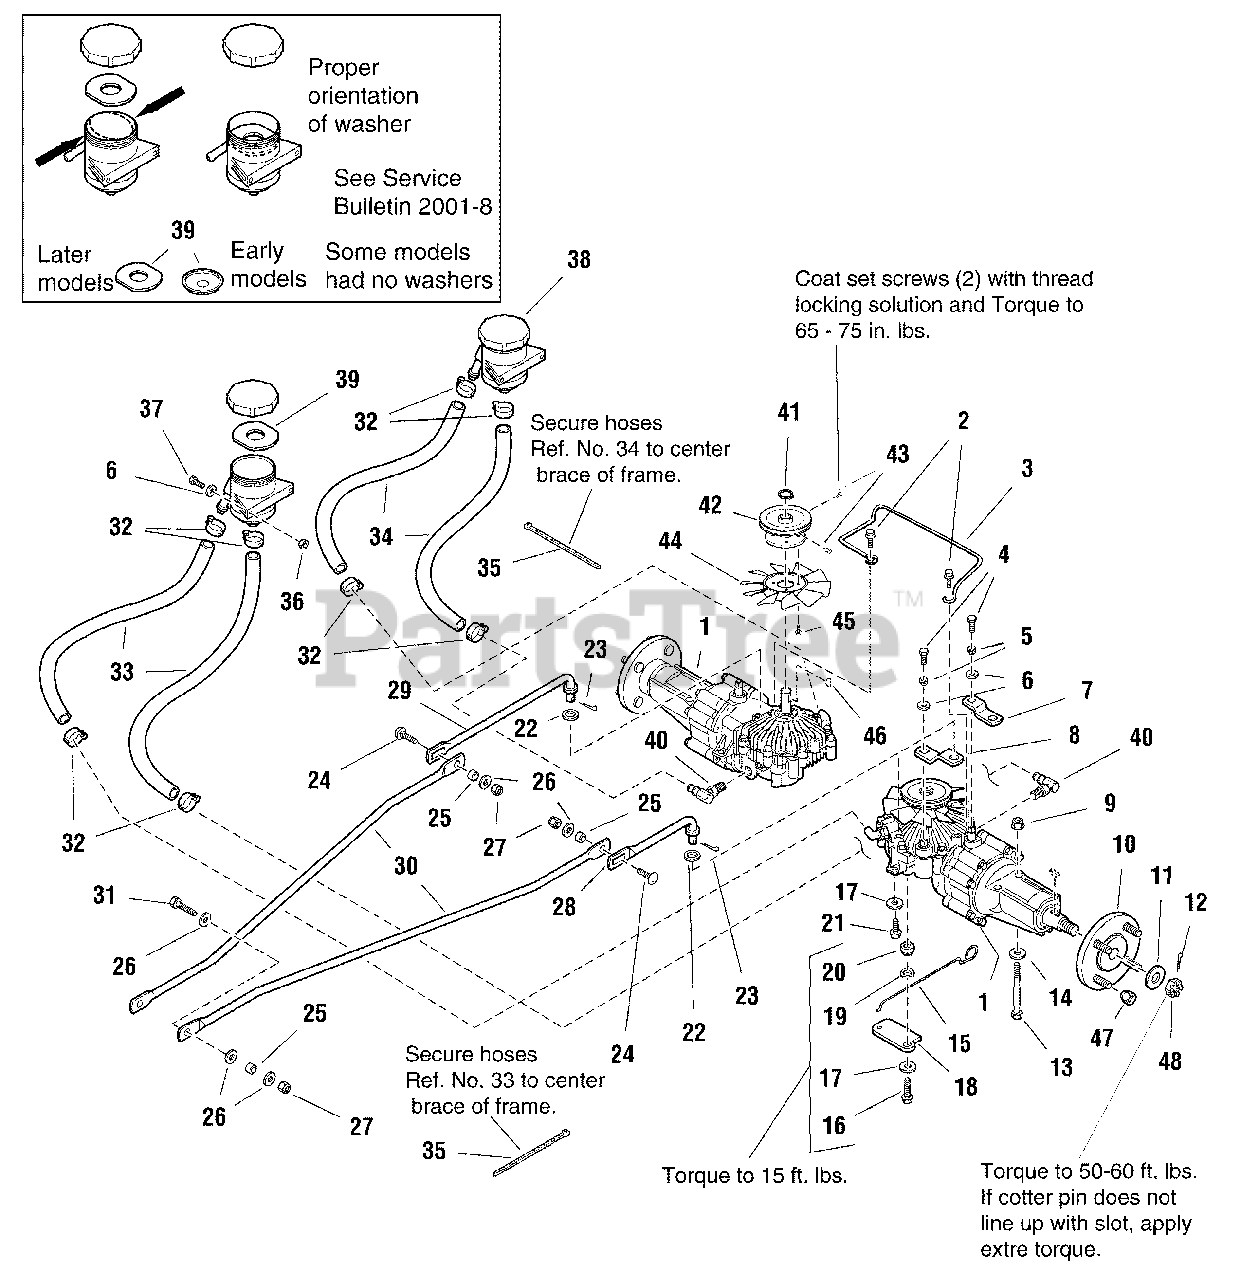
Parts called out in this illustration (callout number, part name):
1	* TRANSMISSION, Eaton 778-028
2	CAPSCREW, Hex Washer Head Taptite, 1/4-20 x 3/4
3	GUIDE, Belt, Transmission
4	CAPSCREW, Hex Head, 1/4-28 x 5/8
5	LOCKWASHER, Spring 1/4
6	WASHER, Plain, 1/4
7	ARM, Transmission Brake
8	BRACKET, Offset
9	NUT, Hex Lock Cent. Fl. 3/8-16
10	HUB, 4 Bolt, Tapered Bore w/Studs
11	WASHER, Plain 3/4
12	PIN, Cotter 1/8 x 1-3/4
13	CAPSCREW, Hex Head, 3/8-16 x 3-1/4
14	WASHER, Plain, 3/8
15	ROD, Actuator, Hydro Release Valve
16	CAPSCREW, Hex Washer Head, Taptite, 5/16-18 x 1-1/4
17	WASHER, 5/16
18	ACTUATOR, Hydro Release Valve
19	WASHER, Wave
21	CAPSCREW, Hex Washer Head, Taptite, 5/16-18 x 7/8, Black
22	WASHER, Plain, 1/2
23	PIN, Cotter, 1/8 x 3/4
24	CARRIAGE BOLT, 5/16-18 x 1
25	SPACER, .328 x .500 x .218
26	WASHER, Plain, 3/8
27	NUT, Hex, Lock ESNA, 5/16-18
28	LINK, Control, Rear LH
29	LINK, Control, Rear RH
30	LINK, Control, Front
31	CAPSCREW, Hex Head, 5/16-18 x 1-1/4
32	CLAMP, Hose
33	HOSE, LH Trans, Top & Bottom
34	HOSE, RH Trans, Top & Bottom
35	TIE, Self Locking
36	NUT, Hex Flange Whiz Lock, 1/4-20
37	CAPSCREW, Hex Head, 1/4-20 x 5/8
38	RESERVOIR ASSEMBLY
39	INNER CAP (Early Models ) Use 1723164 for replacement
39	INNER CAP (Later Models)
40	FITTING, Lower Transmission, Male, 90
41	RING, Retaining
42	PULLEY ASSEMBLY, Transmission
43	SETSCREW, Hex, 1/4-28 x 1/4
44	FAN ASSEMBLY, Transmission
45	CAPSCREW, Hex Washer Head, Taptite, 1/4 -20 x 5/8
46	KEY, Woodruff, 3/16 x 5/8, Hi-Pro
47	NUT, Hex, Lug, 1/2-20 NF
48	NUT, Hex, Slotted (Tapered Shaft)
